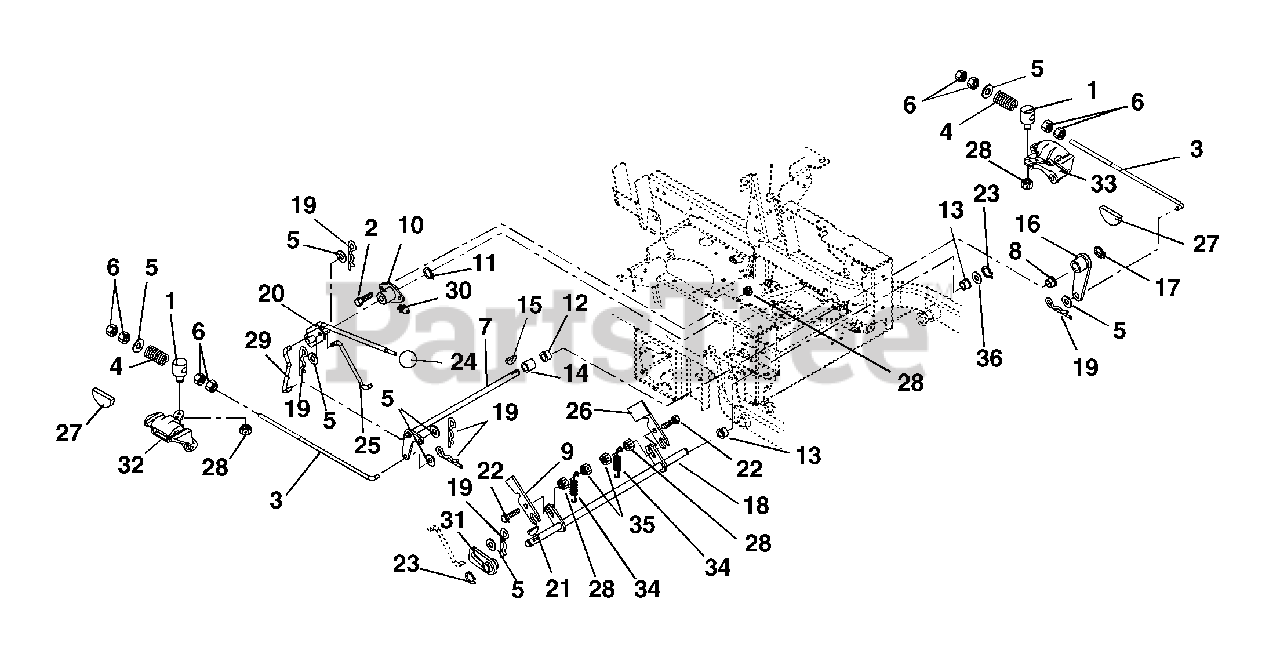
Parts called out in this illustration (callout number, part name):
1	PIN, PIVOT/TRUNNION
2	@BLT-HEX .31-18X.75 GR5 YWZC
3	ROD - BRAKE 12 INCH
4	SG-COMP .142 X .710 X 2.00
5	@WSHR-FL-STL.406X.812X.065 YWZ
6	@NUT-HEX .38-16 YWZC
7	WMT, BRAKE CROSS SHAFT
8	BSHG-FLG .630X1.000X.625 NY
9	SLIDE, INTERLOCKING BRAKE
10	BUSHING, FLANGED (WITH HOLE)
11	RG-RTNG-EXT .625X.050
12	BSHG-FLG .762X1.0X.580X1.48 NY
13	BSHG-FLG.500X.750X.750X1.000BR
14	BSHG-SLV .750X1.000X.750
15	KEY-WDRF .19X.75 HRD #9
16	WMT, BRAKE ARM
17	RG-RTNG-EXT .625X.050
18	WMT, MECHANICAL BRAKE
19	PIN-HAIR, ENDRIES #25 YWZC
20	WMT, BRAKE ACTUATING
21	KEY-WDRF .13X.63 HRD#5
22	@BLT-HEX .31-18X1.25 GR5 YWZC
23	RG-RTNG-EXT .500X.050 (SNAP)
24	KNOB-STEERING LOCK
25	LINKAGE, BRAKE ACTUATING
26	INTERLOCK, SAFETY SWITCH
27	PAD SET, DISK BRAKE
28	@NUT-LK-TOP-FLG .31-18 YWZC
29	LINKAGE, BRAKE ACTUATING
30	FTG-LUBE .25-28X.256 YWZC
31	WMT, PARKING BRAKE HUB
32	BRAKE, RH CALIPER
33	BRAKE, LH CALIPER
34	SG-TENS .061 X .50 X 3.0 WLD 4
35	@NUT-LK-CTR .31-18 YWZC
36	WSHR-FL-STL .505X1.00X.062YWZC
